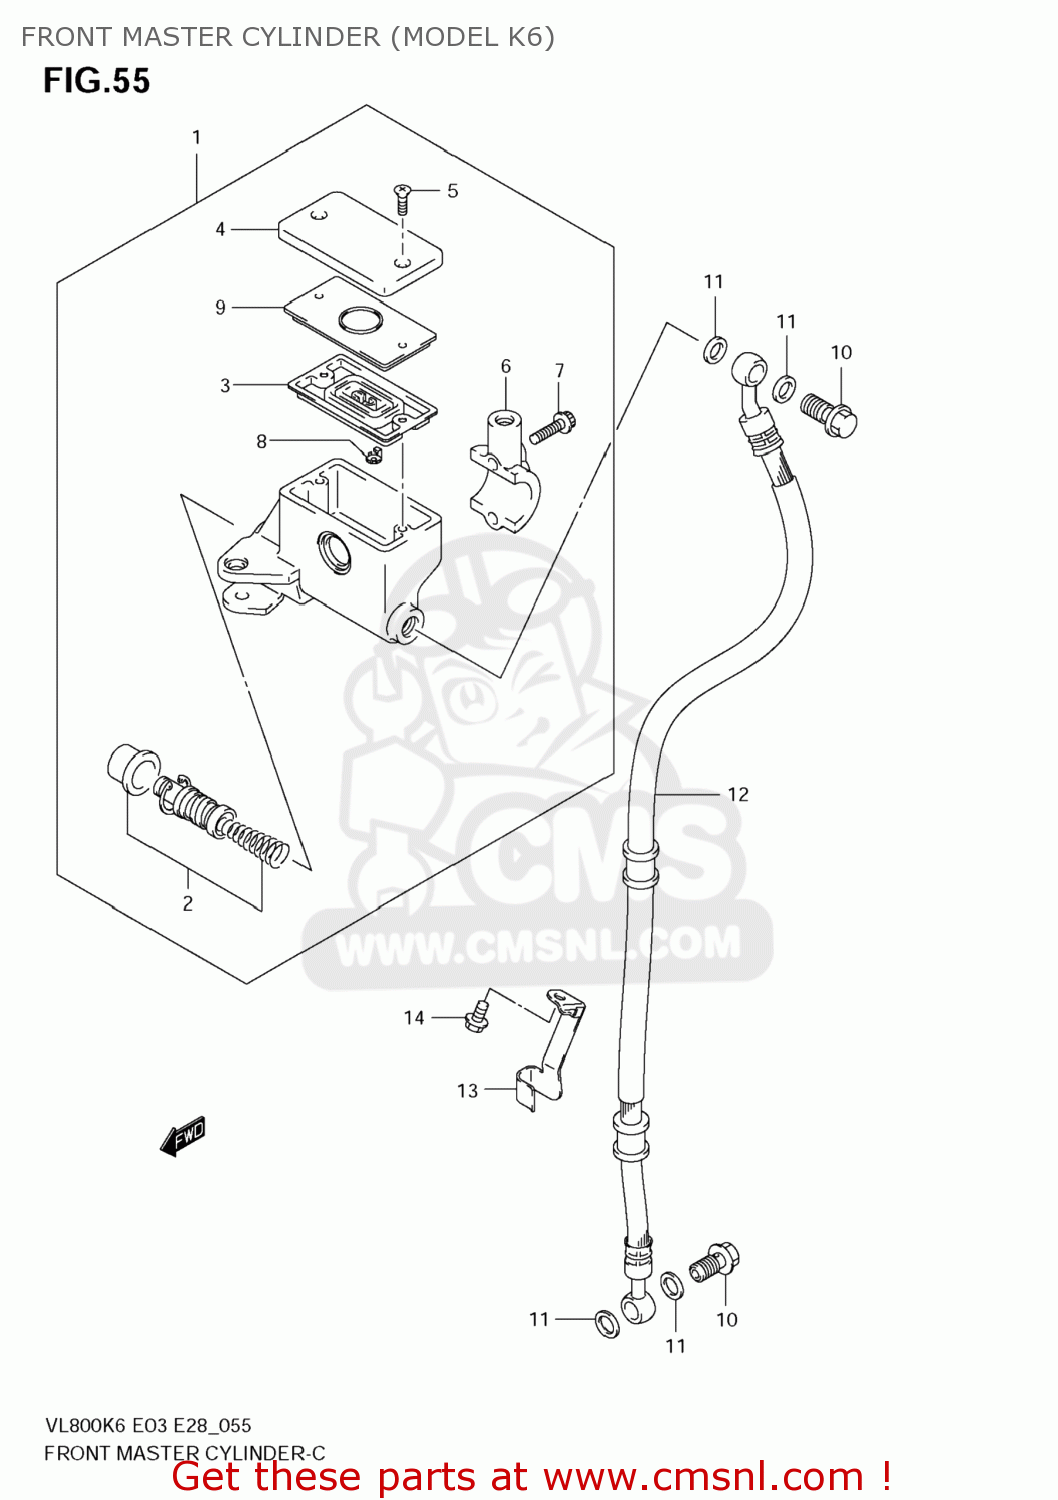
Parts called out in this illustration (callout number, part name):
1	CYLINDER ASSY,FR MASTER
2	PISTON/CUP SET
3	4
4	CAP
5	SCREW
6	HOLDER
7	BOLT
8	PROTECTOR
9	PLATE,DIAPHRAGM
10	BOLT UNION
11	WASHER(10X15X1.5)
12	HOSE,FR BRAKE
13	CLAMP,FR BRAKE HOSE UPR
14	BOLT
